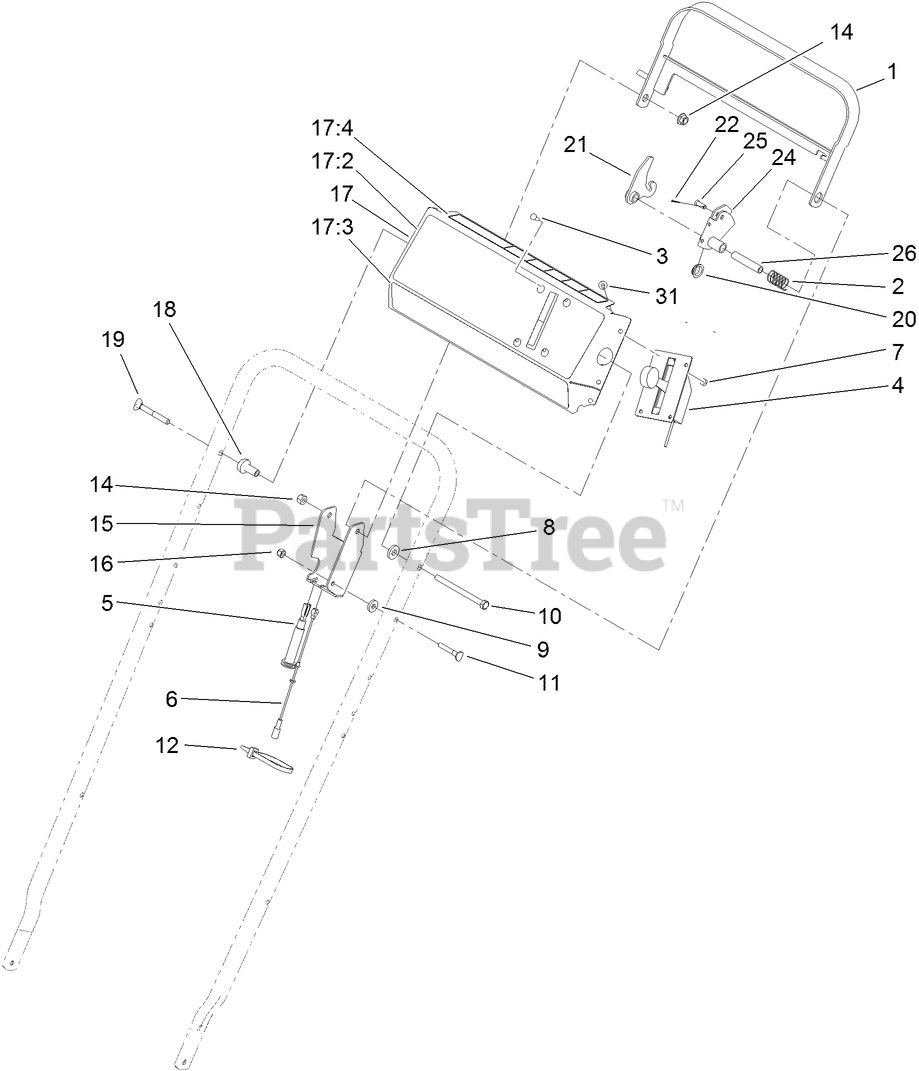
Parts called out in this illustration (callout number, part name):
1	BAR-CONTROL
2	SPRING-CONTROL
3	SCREW-PPH
4	CONTROL-THROTTLE
5	CABLE-TRACTION
6	CABLE-CLUTCH
7	NUT-LOCK, NI
8	SPACER
9	SPACER
10	SCREW-HH
11	SCREW-HANDLE
12	TIE-CABLE
14	NUT-HF, NI
15	BRACKET-CONTROL
16	NUT-LOCK, NI
17	PANEL ASM
17:2	DECAL-PANEL
17:3	DECAL-PANEL
17:4	DECAL-DANGER PANEL
18	SPACER-SUPPORT
19	SCREW
20	BUSHING-FLANGE
21	LEVER-TRACTION
22	PIN-COTTER
24	LEVER-BBC
25	PIN-CABLE
26	SPACER-BRACKET, CONTROL
31	SCREW-HWHTF
